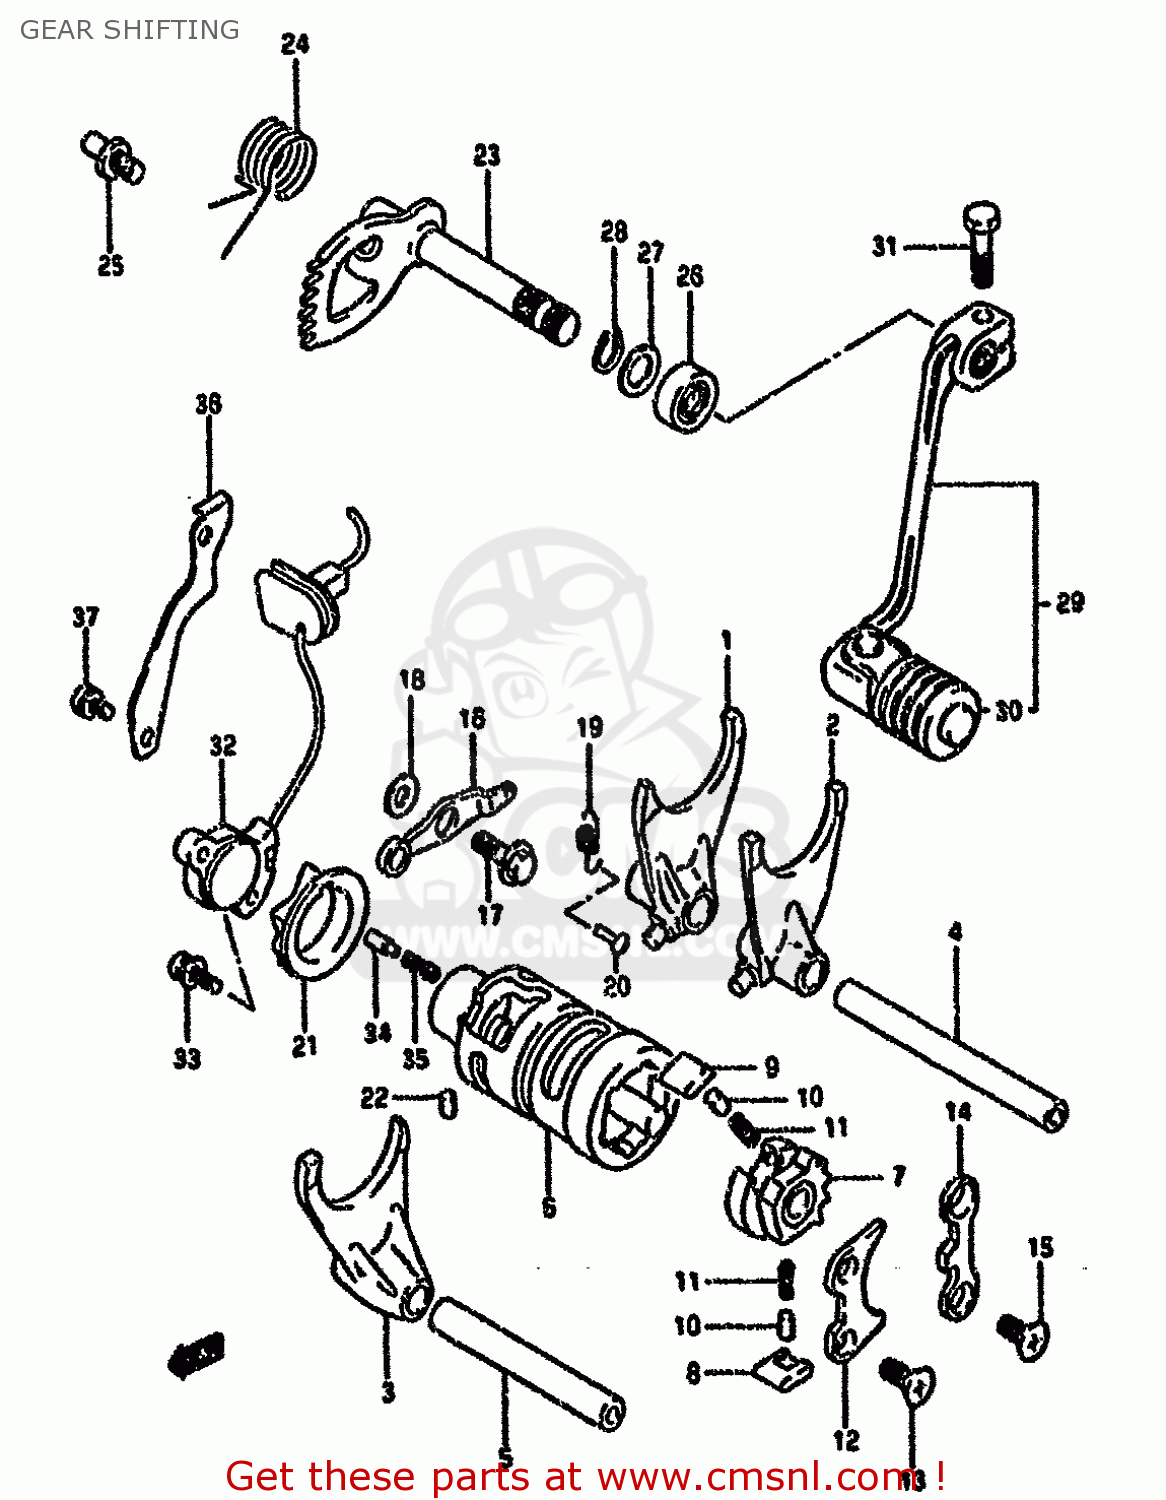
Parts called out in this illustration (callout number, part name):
1	FORK,GEAR SHIFT NO.1
2	FORK,GEAR SHIFT NO.2
3	FORK,GEAR SHIFT NO.3
4	SHAFT,GEAR SHIFT FORK
5	SHAFT,GEAR SHIFT FORK
6	CAM,GEAR SHIFT
7	GEAR,GEARSHIFT CAM DRIVE
8	PAWL,GEAR SHIFT NO.1
9	PAWL,GEAR SHIFT NO.2
10	PIN(5X8)
11	SPRING
12	LIFTER,GEAR SHAFT PAWL
13	SCREW
14	STOPPER,GEAR SHIFT POLE
15	SCREW
16	STOPPER,GEAR SHIFT CAM
17	BOLT
18	WASHER
19	SPRING
20	RIVET
21	PLATE,SHIFT CAM STOPPER
22	PIN
23	SHAFT,GEAR SHIFT
24	SPRING
25	STOPPER,GEAR SHIFT CAM
26	OIL SEAL
27	WASHER
28	CIRCLIP,12 MM
29	LEVER ASSY,GEAR SHIFT
30	RUBBER,GEAR SHIFT PEDAL
31	BOLT
32	BASE ASSY,NEUTRAL SW TERMINAL
33	SCREW
34	PIN(5X15.5)
35	SPRING
36	CLAMP,LEAD WIRE
37	SCREW
